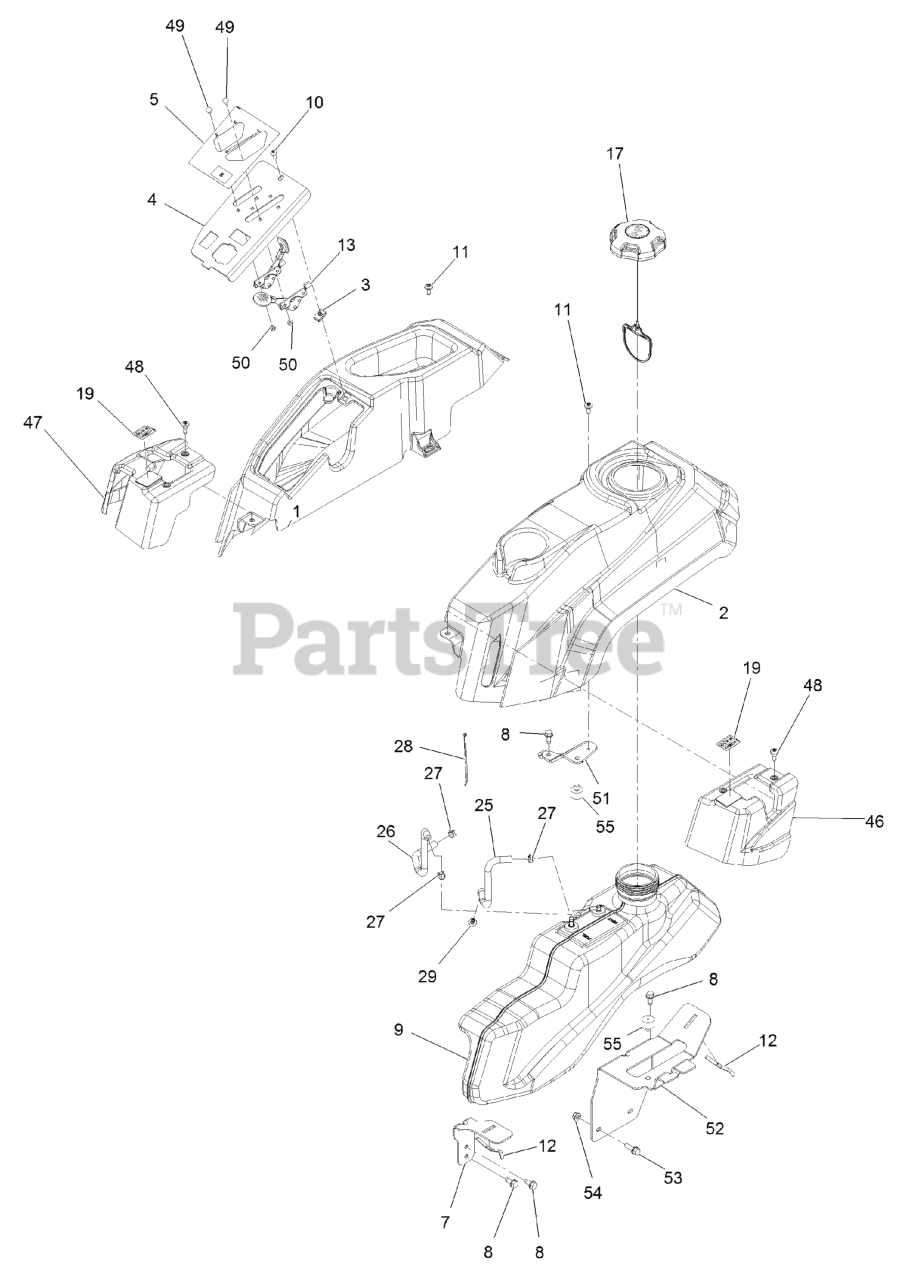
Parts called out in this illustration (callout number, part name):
1	POD-RH, NARROW
2	POD-LH, NARROW
4	PANEL-CONTROL, NARROW
5	DECAL-CONTROL
7	SUPPORT-TANK
8	Screw-HWH 5/16-18 X 3/4 Tf
9	TANK, FUEL
10	SCREW-PRH
11	SCREW-SHOULDER
12	SPRING
13	CABLE-CONTROL, THROTTLE
13	CABLE-CONTROL, CHOKE
17	CAP-FUEL, RATCHETING
19	DECAL-MOTION CONTROL
25	HOSE-FUEL
26	HOSE-FUEL
27	CLAMP-HOSE
28	TIE-CABLE
29	ADAPTOR-ORIFICE
46	Cover, Motion Control LH
47	Cover, Motion Control RH
48	SCREW-SHOULDER
49	BOLT-CARR
50	NUT-LOCK, NI
51	BRACKET-CLAMP
52	BRACKET-SUPPORT TANK
53	SCREW-HHF
54	NUT-HF, NI
55	BUMPER-GROMMET
